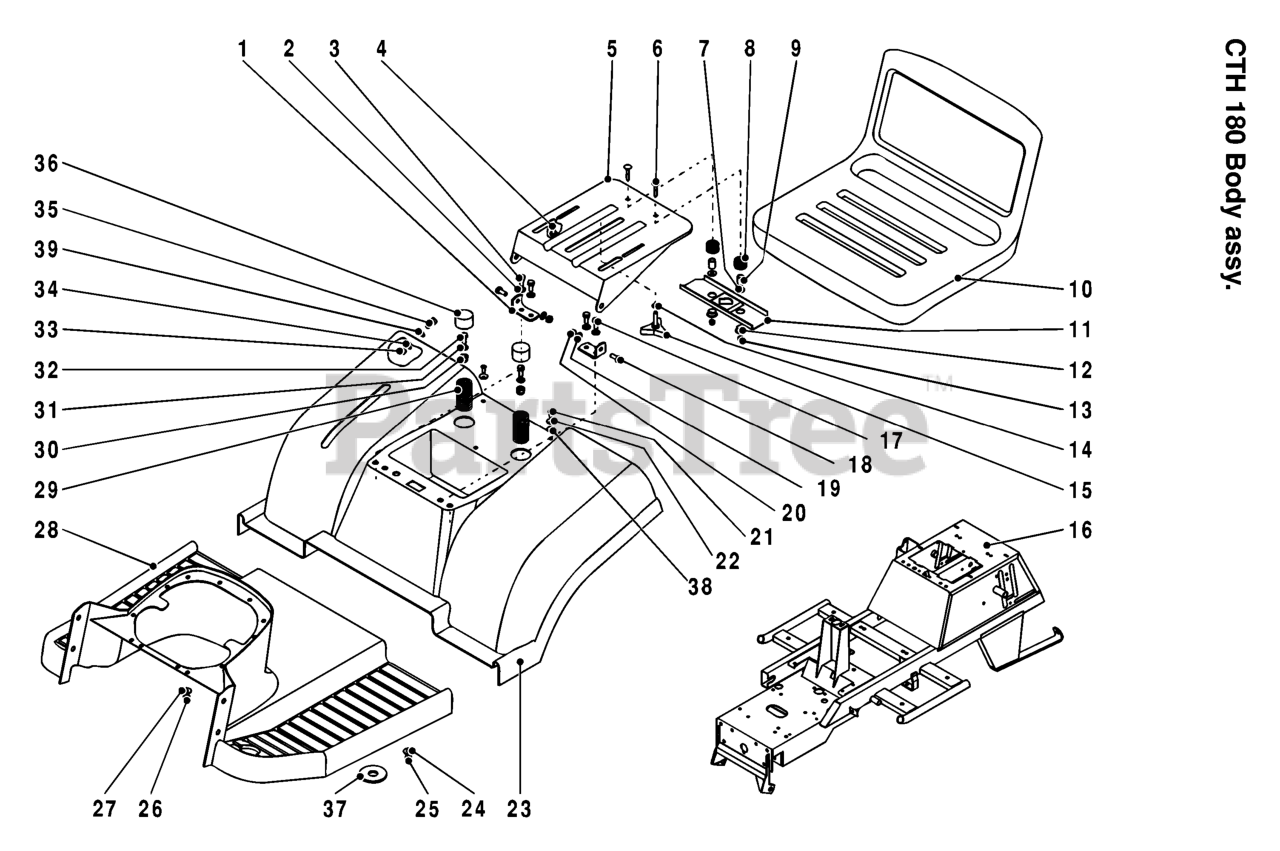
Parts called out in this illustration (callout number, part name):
2	SPRING WASHER
7	WASHER - M6
10	SEAT
13	Blocking nut M 6 Z
15	KNOB 1/2" YT
20	NUT
21	HEX BOLT
22	Washer 0 5.3
24	WASHER
30	NUT
